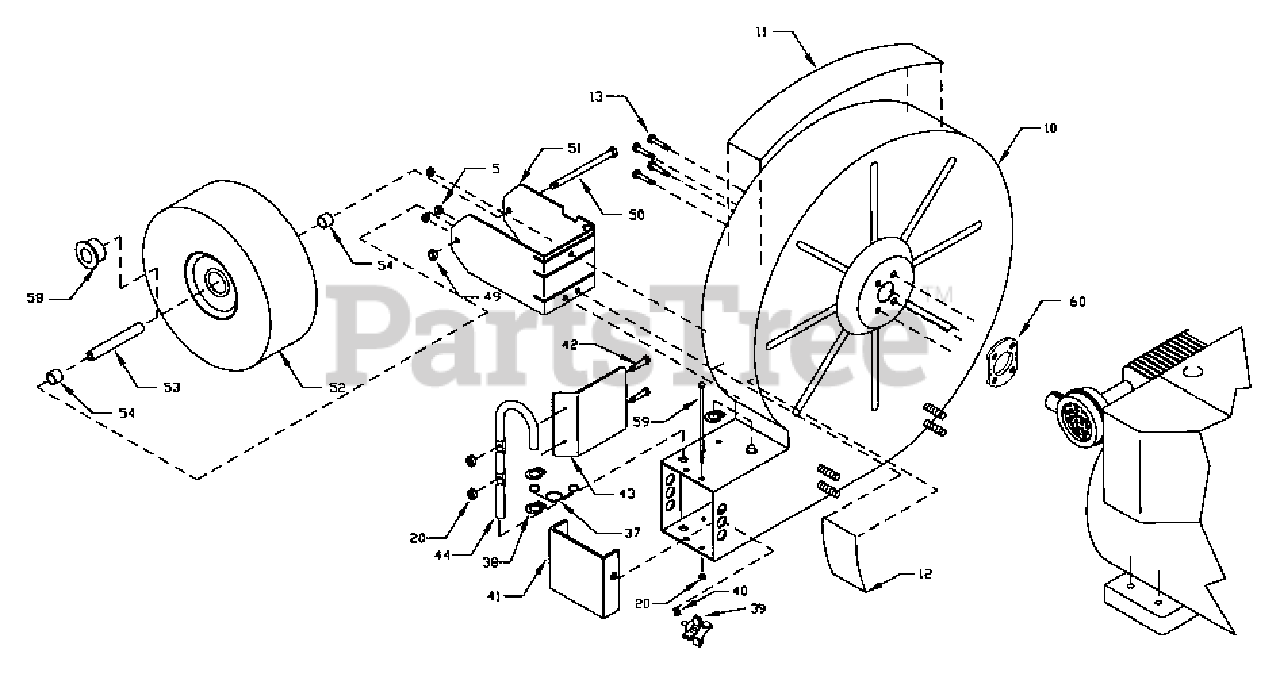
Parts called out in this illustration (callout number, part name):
10	8, 9 HP Housing
11	Gravely Housing Label - 8 HP
12	Warning Label
13	5/16-24 x 3/4 Whiz Head Flange Bolt
20	10-32 2-Way Lock Nut
37	Deflector Spring
38	Retaining Ring
40	5/16 External Tooth Lock Washer
41	8, 9 HP Side Deflector
42	10-32 x 5/8 Serrated Flange Screw
43	8, 9 HP Internal Deflector
44	Deflector Handle
49	3/8-16 2-Way Lock Nut
50	3/8-16 x 5 1/4 Bolt
51	Wheel Bracket
52	Pneumatic Wheel Symmetrical
53	Pneumatic Wheel Sleeve
54	Front Wheel Bracket Spacer
58	Pneumatic Wheel Bearing
59	10-32 x 5 1/2 Hex M/S
